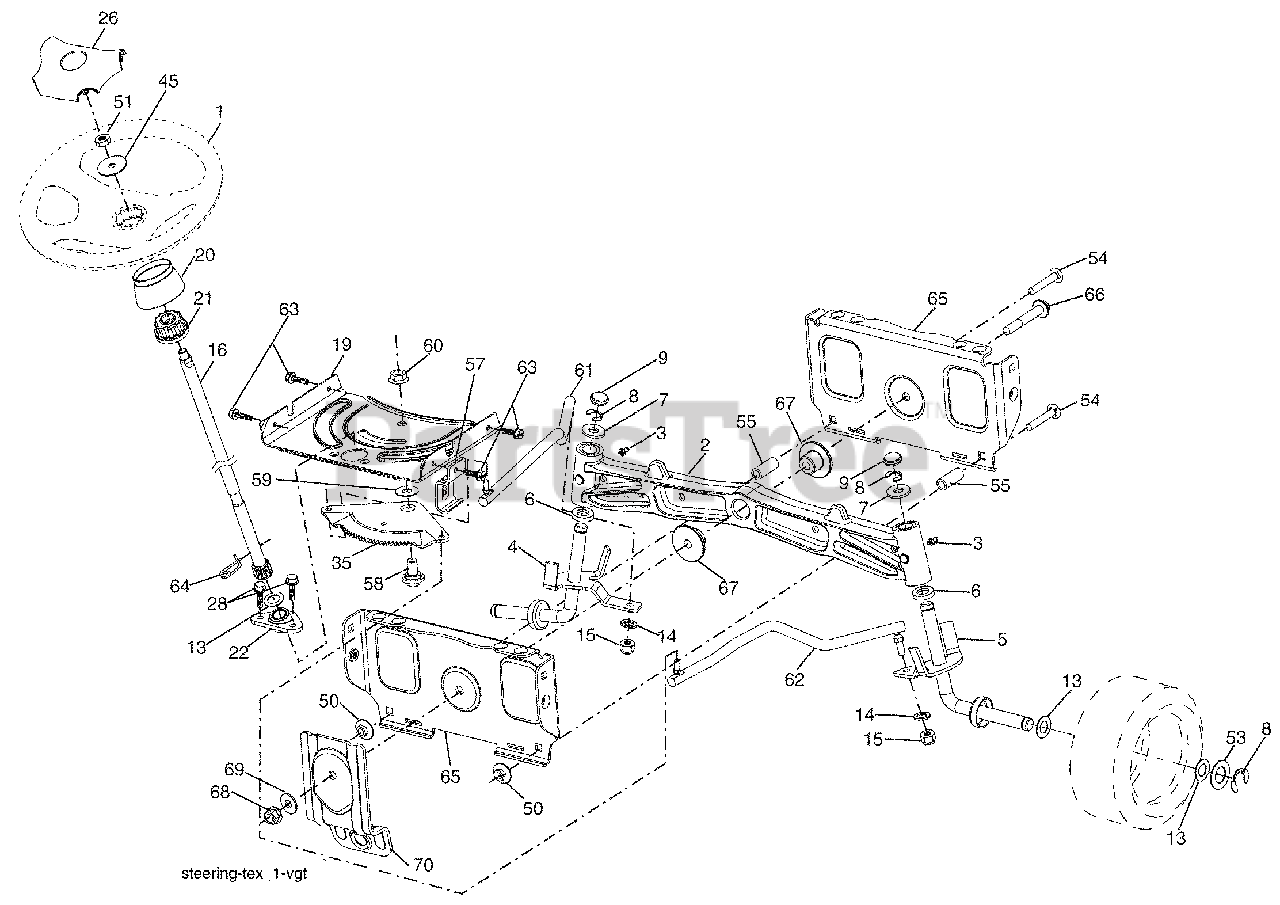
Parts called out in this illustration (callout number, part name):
1	Wheel, Steering
2	Axle Asm., Front
3	Fitting, Grease
4	Spindle Asm., LH
5	Spindle Asm., RH
6	Bearing, Race Thrust Harden
7	Washer 25/32 x 1-5/8 x 16 Ga.
8	Ring, Klip #T5304-75
9	Cap, Spindle
13	Washer 25/32 x 1-1/4 x 16 Ga.
14	Washer, Lock Hvy Hlcl Spr 3/8
15	Nut, Crown Lock 3/8-24 unf
16	Shaft Steering
19	Plate Steering
20	Boot, Steering
21	Adapter, Wheel Steering
22	Bushing, Strg. Blk
26	Insert, Wheel Steering
28	Screw 3/8-16 x 3/4
35	Gear, Sector Plate
45	Washer 11/32 ID x 2-3/8 x 12 Ga.
48	Screw 3/8-16 x .75
50	Nut Lock 3/8-16 unc
51	Nut Hex Jam Toplock 1/2-20 unf
53	Washer Hardened.793 x 1.637 x .060
54	Bolt Hex 3/8-16 unc x 2-1/4
55	Spacer Brace Axle
57	Bracket Upstop
58	Bolt Shoulder Sector Pivot CFM
59	Washer Thrust Sector Steering
60	Nut Flange Lock 5/8-11
61	Draglink LH
62	Draglink, RH
63	Screw 5/16-18 x 3/4
64	Retainer Clip Spring Steering
65	Brace Axle Front
66	Bolt Hex Fghd 7/16-14 x 3 Serr
67	Bushing PM Front Axle
68	Nut Lock Flange 7/16-14 Gr. 5
69	Washer 1.5 x .505 x .118
70	Bracket Deck Susp. Front
